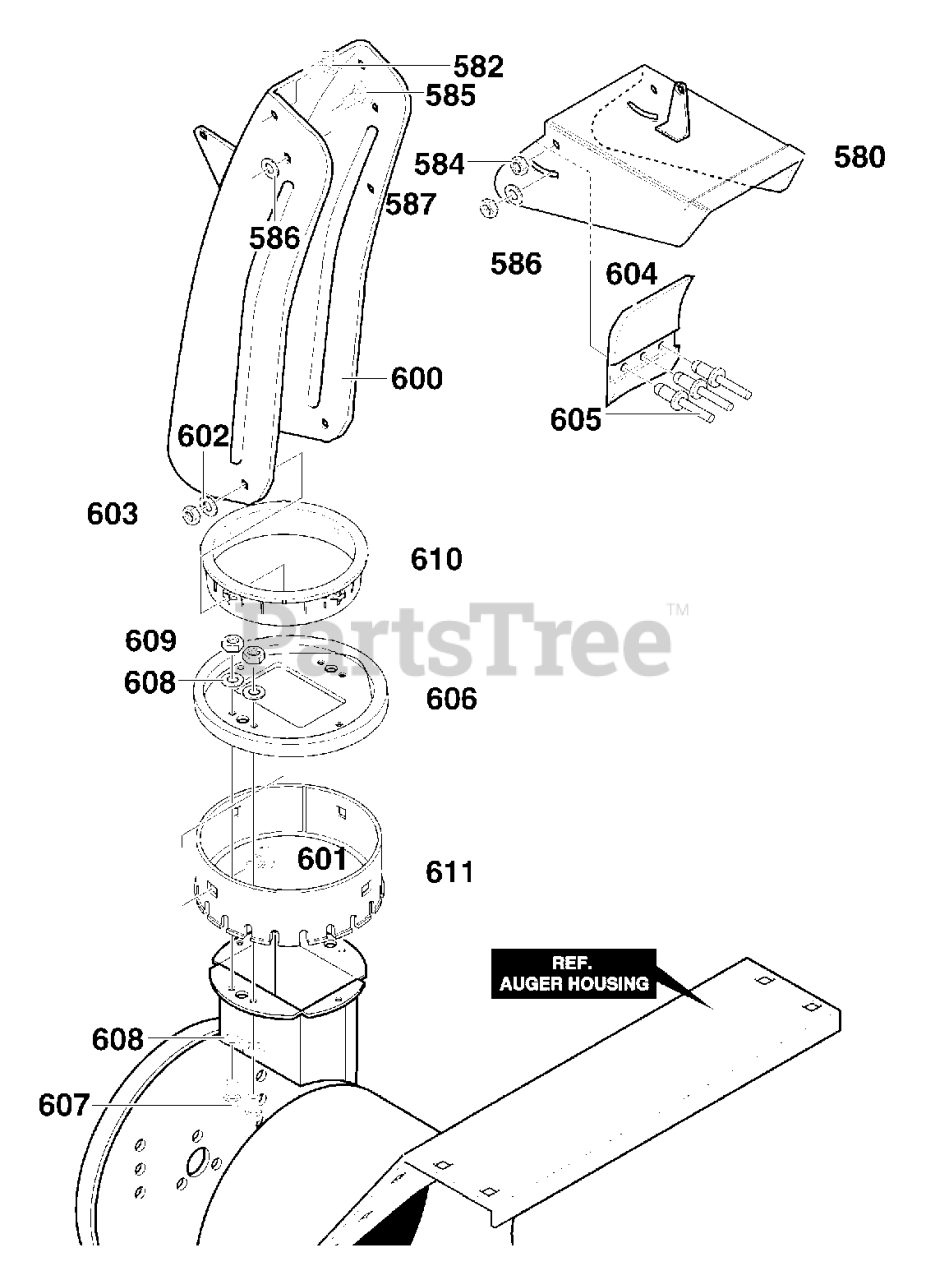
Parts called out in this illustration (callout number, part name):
580	UPPER CHUTE
582	SCREW, 5/16-18 x 0.75
584	NUT, 5/16-18 REGHEXCTRLK
586	PLASTIC WASHER
587	NUT, 5/16-18 REGHEXCTRLK
600	LOWER CHUTE
600	CHUTE, ASSEMBLY
601	BOLT, 5/16-18X1.00
602	FLATWASHER .349X.69X.066
603	NUT, 5/16-18
606	COLLAR, CHUTE
607	SCREW, 1/4-20X .75
608	FLATWASHER .281X .63X.065
609	NUT, 1/4-20 HEX NYLOCK
610	RETAINER, RING INNER
611	RETAINER, RING OUTER
